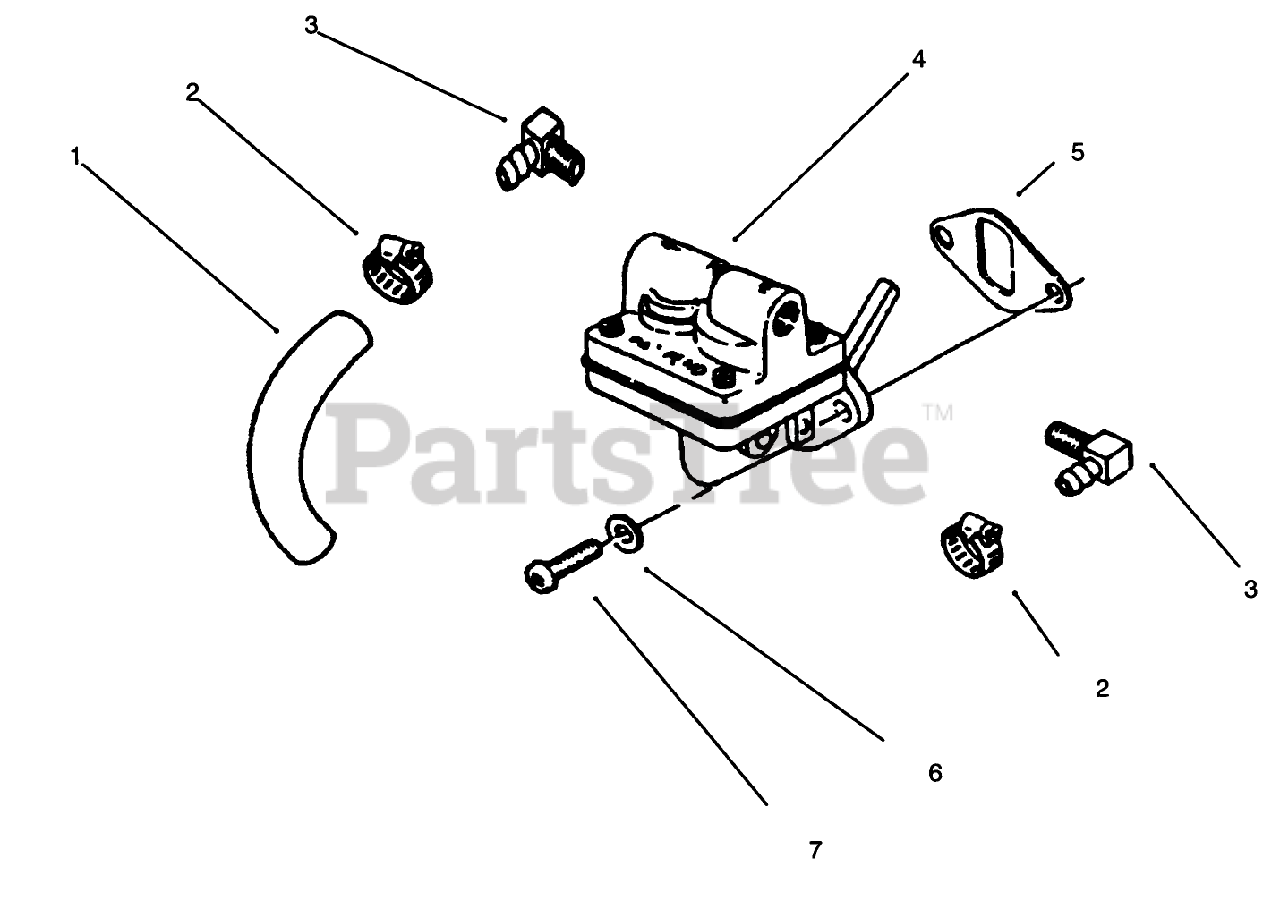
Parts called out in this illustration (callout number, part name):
1	KOHLER 25-353-01
2	KOHLER X-426-9
3	KOHLER 25-155-02
4	KOHLER 47-559-08
5	KOHLER 25-041-05
6	KOHLER X-25-63
7	KOHLER X-174-2
